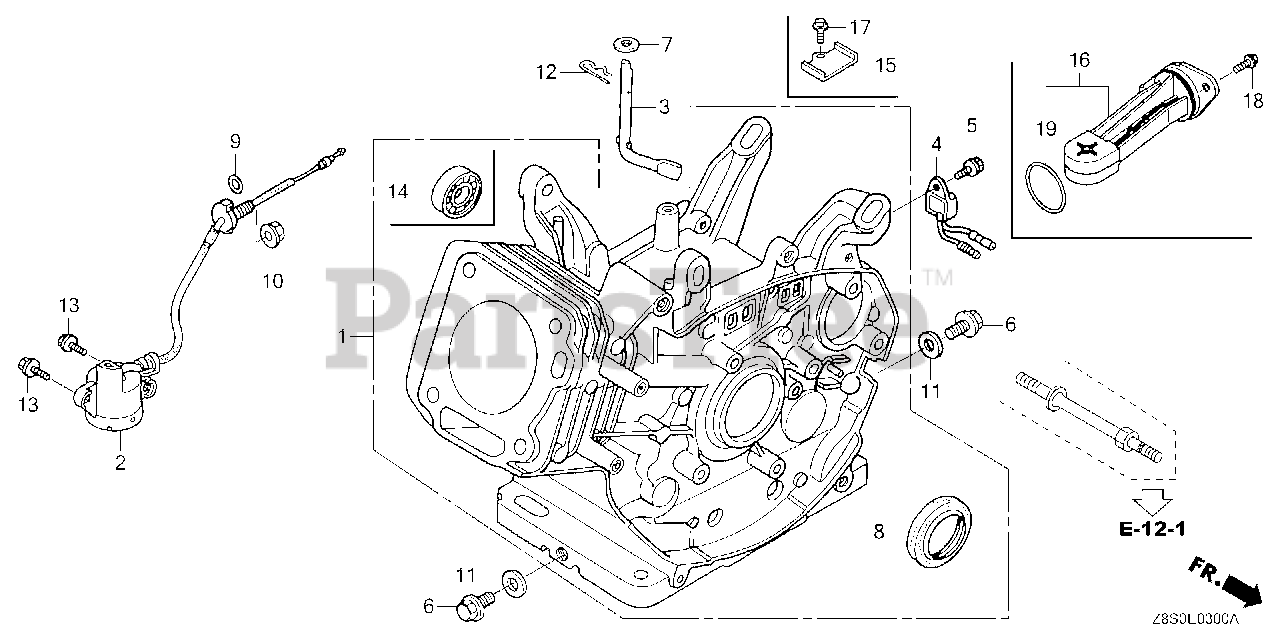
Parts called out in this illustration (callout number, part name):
1	CYLINDER ASSY.
2	SWITCH ASSY., OIL LEVEL
3	SHAFT, GOVERNOR ARM
6	BOLT, DRAIN PLUG
7	WASHER (8.2X17X0.8)
8	OIL SEAL (30X46X8) (NOK ASIA)
8	OIL SEAL (30X46X8)
9	O-RING (14MM) (ARAI) Use up to Engine SN 2949254.
9	O-RING (14MM) (NOK)
10	NUT, FLANGE (10MM)
11	WASHER, DRAIN PLUG (12MM)
12	PIN, LOCK (10MM)
13	BOLT, FLANGE (6X12) Use up to Engine SN 1543277.
14	BEARING, RADIAL BALL (6202)
